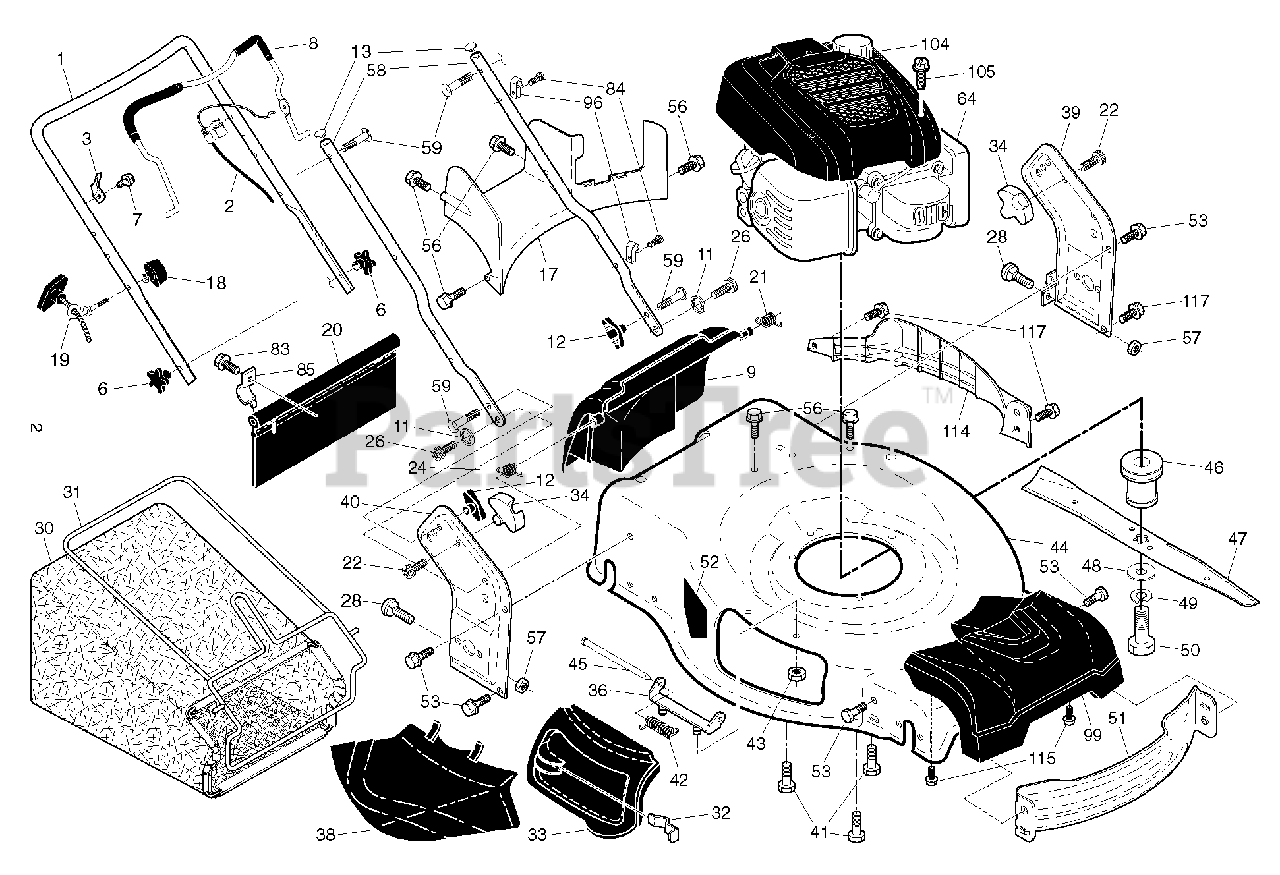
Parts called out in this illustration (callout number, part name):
1	HANDLE.UP.3POS.BS.AW2.GREY
2	CABLE.MZR.50.SNAP-IN
3	BRACKET.UPSTOP.RT
6	KNOB.HANDLE.PLASTIC.STAR.BLACK
8	BAIL.OVER.MOLD.ERGO.MZR.ORANGE
9	DOOR.REAR.ASM.22+.HUSQ.FG/RGD
11	E-RING.12MM.SHAFT
12	KNOB, DEFLECTOR
13	PLUG.PLASTIC.7/8".14-20.GAUGE
17	BAFFLE.REAR.22+RGD.AWD.PLASTIC
18	T-KNOB.NEW ROPE GUIDE
19	GUIDE.ROPE.BLK.ZINC.CHROM
20	SKIRT.REAR.22+RGD.HIGH WHEEL
21	SPRING.LH.BLACK
22	SCREW.PAN.HEAD.#10
24	SPRING.RH.GRAY
26	SCREW,DOOR/HANDLE.PIVOT
28	BOLT.CARRIAGE.LN.5/16-18X.5/8
30	GBAG.BA85028EM.NOFRAME.GRY/SLV
31	FRAME.GBAG.22+.BLK
32	LATCH.DOOR.ZINC
33	DOOR.MULCH.22 PLUS.HUSQ.GREY
34	BRACKET.GRASSBAG.ATTACHING.BLK
36	BRACKET.ASM.HINGE.21.FWGD.
38	DEFLECTOR.CLIPPING.22.BLACK
39	BRACKET.ASM.HANDLE.LT.22+.GREY
40	BRACKET.ASM.HANDLE.RT.22+.GREY
41	BOLT 3/8-16X1-1/8
42	SPRING.TORSION
43	NUT.HEX.FLANGE.1/4
44	KIT.HSG.22+AWD.MC.WO.668.TRI
45	ROD.HINGE.21
46	ADAPTER.BLADE.25MM.3MPH
47	BLADE REAPER, 22 IN RUST
48	WASHER,HARDEN
49	LOCKWASHER
50	SCREW, HEX HD 3/8-24 X 1-3/8
51	BAFFLE.FRONT.22.PLUS
52	DANGER DECAL
53	BOLT.5/16HEX.WHS.HD
56	SCREW.HX.13X.750
57	NUT.FLANGE.5/16
58	HANDLE.LOWER.22+.BT.GRAY
59	BOLT, HANDLE 5/16-18X1.75
83	TAPPING SCREW
84	FASTENER.PUSH.O.250X0.783
85	BRACKET.SKIRT.22+.BZP
96	CLIP.CABLE.BLK
99	COVER.ASSEMBLY.FRONT.22+AWD
104	SHROUD.ASM.HONDA.HUSQVARNA
105	SCREW.SHROUD.HONDA
114	BUMPER.LEFT SIDE 22+.498
115	SCREW.SHOULDER.5/16X1.375
117	BOLT.HEX.HD.WASHER.5/16-18X.75
